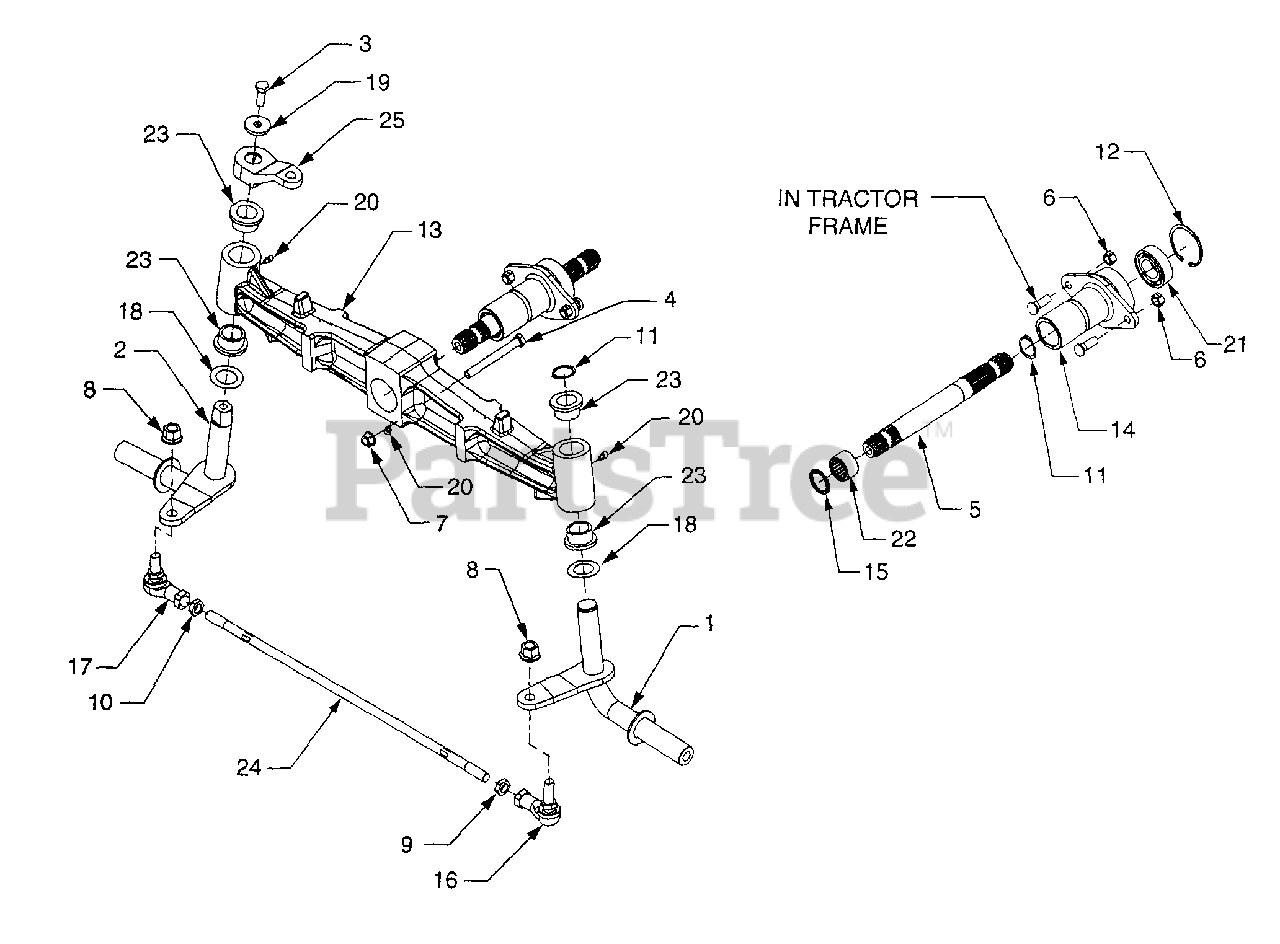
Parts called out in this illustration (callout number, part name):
1	Axle, RH Steering
2	Axle, LH Steering
3	Screw, Hex Cap 3/8-24 x 1.0 GR8
4	Screw, Hex Cap 3/8-16 x 3.5 GR5
5	Shaft, Splined
6	Nut, Hex Center Lock, 3/8-24
7	Nut, Hex Flange Lock, 3/8-16
8	Nut, Hex Flange Lock, M12 x 1.75
9	Nut, Hex - RH, M12 x 1.75
10	Nut, Hex - LH, M12 x 1.75
11	Snap Ring, 1.0 Dia. Shaft
12	Retaining Ring, Internal, 2.0
13	Pivot Axle
14	Axle Carrier
15	Seal, Grease, 1.31 x 1.0
16	Ball Joint, 12MM x 1.75 RH
17	Ball Joint, 12MM x 1.75 LH
18	Washer, Flat, 1.03 x 1.62 x .030
19	Washer, Flat, .406 x 1.25
20	Fitting, Lube, 3/16 Drive
21	Bearing, Ball
22	Bearing, Needle
23	Bearing, Flange
24	Tie Rod, M12 x 1.75 RH & LH
25	Steering Arm
